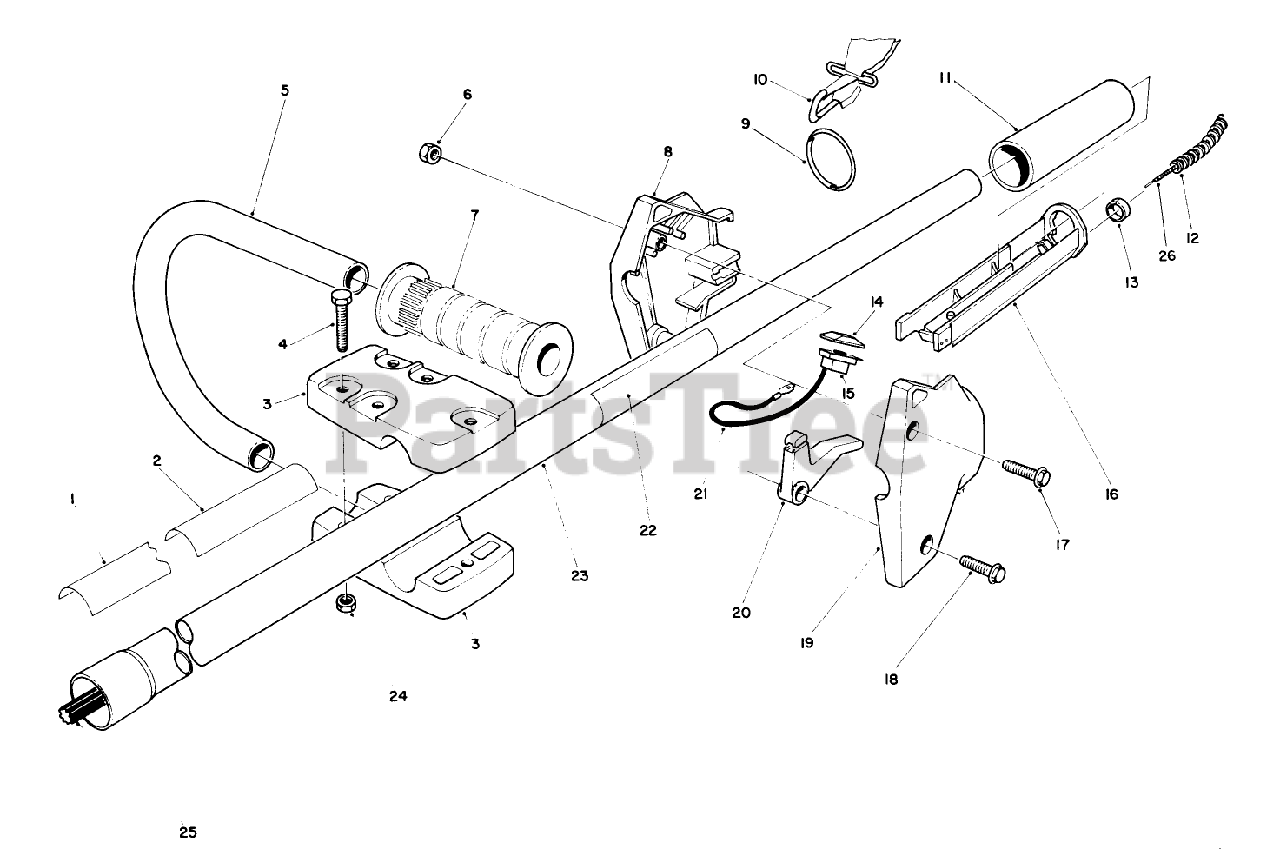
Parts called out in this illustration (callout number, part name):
3	CLAMP
4	SCREW-HH
5	J HANDLE TUBE
6	NUT-LOCK, NI
8	THROTTLE HSG.R H
9	RING-HARNESS
11	GRIP - RUBBER
12	CABLE COVER
13	RING FITTING
15	SWITCH
16	TROUGH 1"
18	SCREW-HWH
22	DECAL-INSTRUCTION
24	NUT-LOCK, NI
25	SPLINE SHAFT
